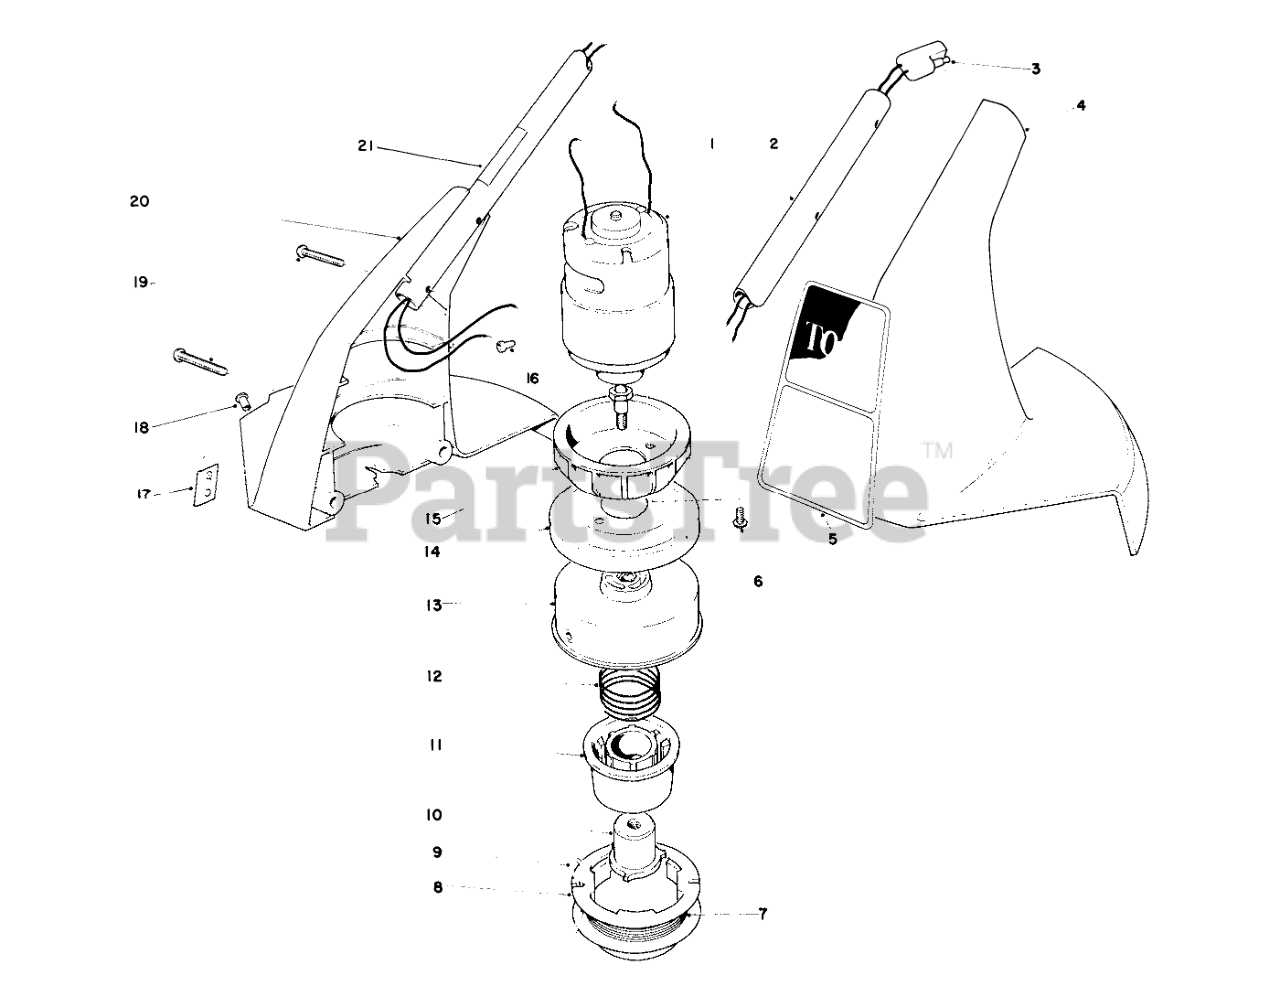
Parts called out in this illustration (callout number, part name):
1	MOTOR ASM
2	EXTENSION HANDLE
3	WIRING HARNESS LOWER
4	Housing-L.H.
5	Decal-CL-710
6	Screw
7	Prewound Spool
8	CAP-SPOOL
9	Line-Cutting (30- .05 Dia.)
10	DRIVER
11	CORE - SPOOL
12	Spring
13	Drum w/Eyelet
14	DRUM CUP
15	Casting-Heat Sink
16	Connector
17	Knife Blade
18	Rivet
19	SCREW-PLASTITE
20	R.H. Motor Housing (Incl. Ref. #17 & 18)
21	REP. SERIAL PLT
